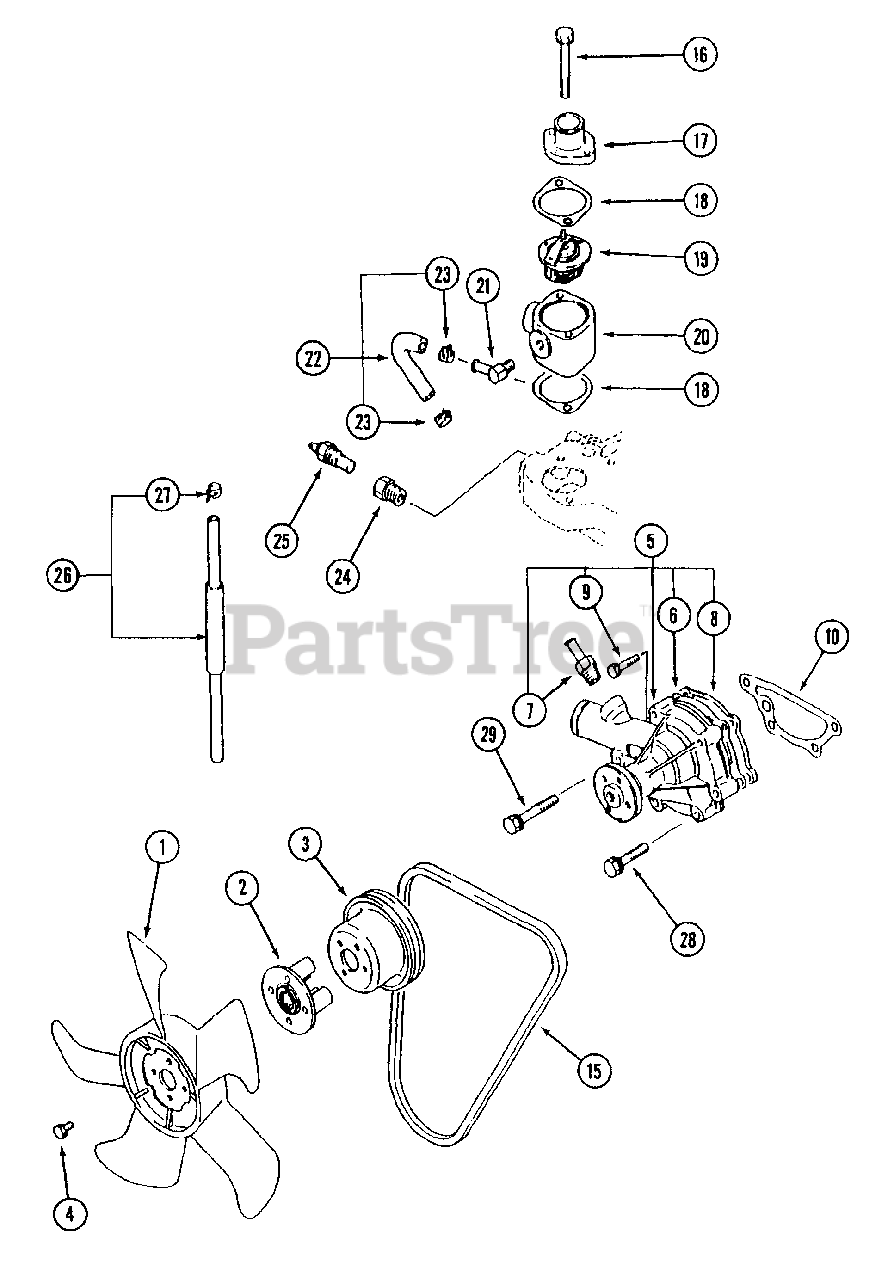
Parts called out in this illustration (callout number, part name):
1	Fan, Cooling
2	Spacer, Fan
3	Pulley, Water Pump
4	Bolt, w/Washer
5	Pump Ass'y., Water
6	Gasket, Water Pump
7	Joint, Water Pump
8	Plate, Water Pump
9	Bolt, w/Washer
10	Gasket, Water Pump
16	Bolt, w/Washer
17	Fitting, Water Outlet
18	Gasket
19	Thermostat
20	Fitting, Thermostat
21	Joint, Water Hose
22	Hose Ass'y., Wate Bypass
24	Joint, Gauge Unit
25	Gauge Unit, Water Temp
26	Hose Ass'y., Water Drain
28	Bolt, Washer Ass'y.
29	Bolt, Washer Ass'y.
